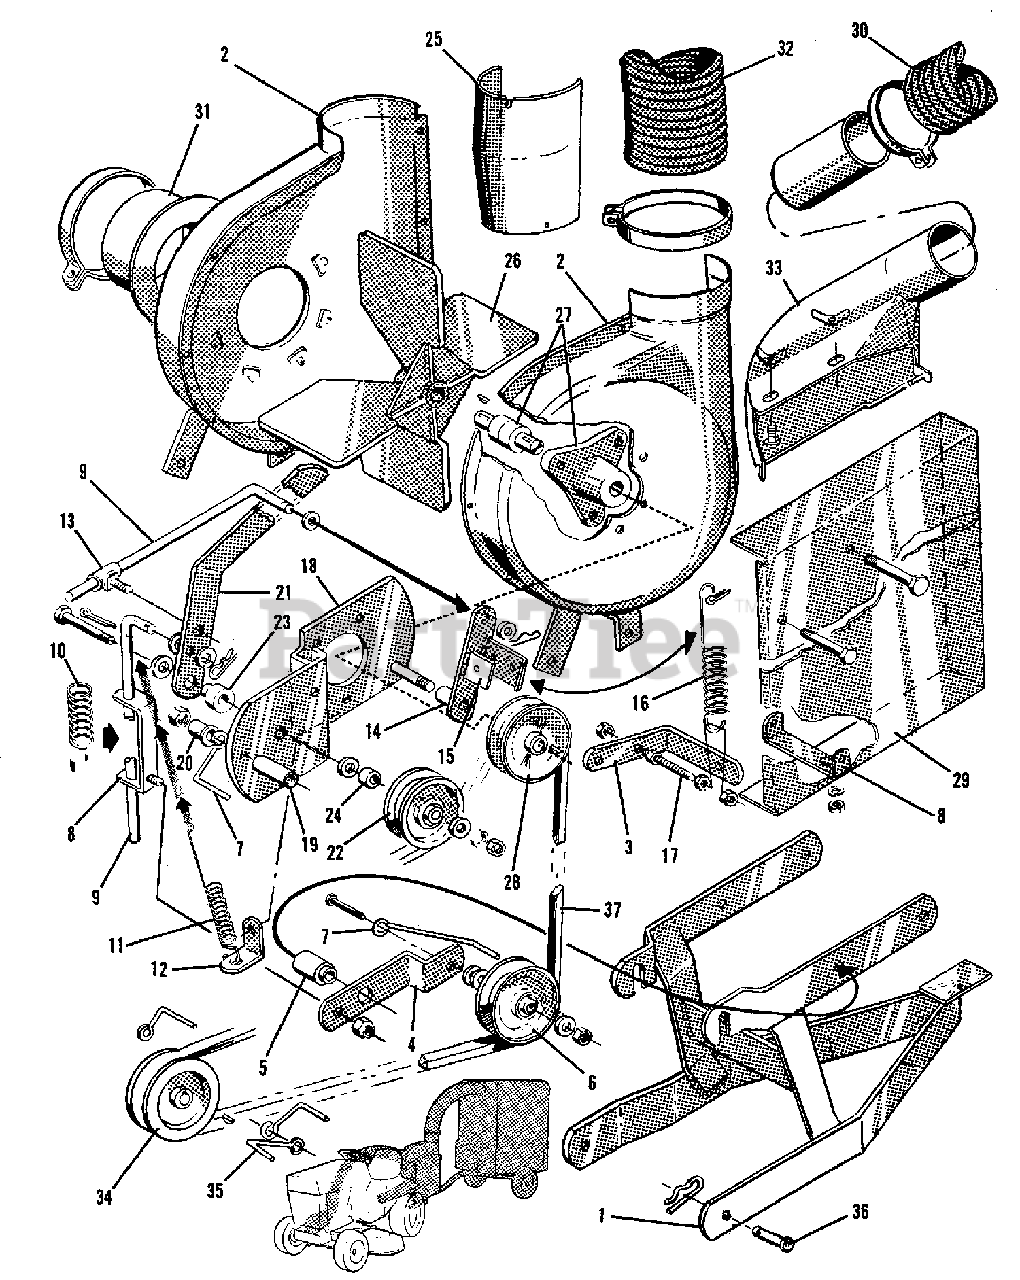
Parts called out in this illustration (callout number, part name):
1	SUPPORT ASSEMBLY, Blower Housing
1	CAPSCREW, 3/8 NC x 1-1/4
1	LOCKWASHER, 3/8
1	NUT, 3/8NC
2	HOUSING ASSEMBLY, Inlet Half (L.H.)
2	HOUSING ASSEMBLY, Blower Half (R.H.)
2	CAPSCREW, 1/4NC x 1/2
2	LOCKWASHER, 1/4
2	NUT, 1/4NC
3	BRACKET, Cover
3	CAPSCREW, 5/16NC x 3/4
3	CAPSCREW, 3/8 NC x 1-1/4
3	LOCKWASHER, 5/16
3	LOCKWASHER, 3/8
3	NUT, 5/16NC
3	NUT, 3/8NC
4	ARM, Idler Support
4	NUT, 5/16NC, Lock
5	PIVOT, Idler Arm
5	CAPSCREW, 3/8NC x 3
5	WASHER, 13/32 x 1-1/2 x 11 Ga.
5	LOCKWASHER, 3/8
5	NUT, 3/8NC
6	PULLEY, Idler
6	CAPSCREW, 3/8 NC x 1-1/2
6	WASHER, 13/32 x 7/8 x 14 Ga.
6	LOCKWASHER, 3/8
6	NUT, 3/8NC
7	STOP, Belt
8	BRACKET ASSEMBLY, Support
8	CAPSCREW, 5/16NC x 3/4
8	LOCKWASHER, 5/16
8	NUT, 5/16NC
8	NUT, 5/16NC, Lock
9	ROD, Control
9	COLLAR, Set
9	SETSCREW, 1/4NC x 3/8, Square Head
9	PIN, Quick
9	WASHER, 11/32 x 7/8 x 16 Ga.
10	SPRING, Compression
11	SPRING, Tension
11	PIN, Cotter
12	BRACKET, Spring Mounting
12	CAPSCREW, 1/4NC x 1
12	WASHER, 1/4, Plain
12	LOCKWASHER, 1/4
12	NUT, 1/4NC
13	GUIDE ASSEMBLY, Rod
13	NUT, 5/16NC, Lock
14	LEVER ASSEMBLY, Brake
15	SCREW, #10NC x 5/8
15	LOCKWASHER, #10
15	NUT, #10NC
16	SPRING, Tension
16	PIN, Cotter
17	STUD, Spring Retaining
17	NUT, 3/8NC, Lock
17	LOCKWASHER, 3/8
17	NUT, 3/8NC
18	BRACKET ASSEMBLY, Idler Support
18	WASHER, 13/32 x 7/8 x 14 Ga.
18	NUT, 3/8NC, Lock
18	CAPSCREW, 3/8NC x 1
18	LOCKWASHER, 3/8
19	SPACER, Long
19	CAPSCREW, 5/16NC x 4
19	CAPSCREW, 5/16NC x 2-1/2
19	WASHER, 11/32 x 7/8 x 16 Ga.
19	LOCKWASHER, 5/16
19	NUT, 5/16NC
20	SPACER, Short
21	LEVER, P.T.O.
22	PULLEY, Idler
22	CAPSCREW, 3/8NC x 2-1/2
22	WASHER, 13/32 x 1-1/2 x 11 Ga.
22	WASHER, 13/32 x 7/8 x 14 Ga.
22	LOCKWASHER, 3/8
22	NUT, 3/8NC
23	SPACER, Pivot
25	DEFLECTOR
25	SCREW, #10NC x 3/8, Self-Tap
26	FAN ASSEMBLY, Blower
26	SETSCREW, 5/16NC x 1/2, Square Head
26	KEY, #9, Woodruff
27	FLANGE ASSEMBLY
28	PULLEY, Blower Drive
28	SETSCREW, 5/16NC x 5/16
28	KEY, #9, Woodruff
29	COVER, Belt Drive
30	HOSE, Intake
30	CLAMP, Hose
30	SCREW, 1/4NC x 2-3/4, Round Head
30	LOCKWASHER, 1/4
30	NUT, 1/4NC
31	FLANGE, Hose
32	HOSE, Exhaust
32	CLAMP, Hose
32	SCREW, 1/4NC x 2-3/4, Round Head
32	LOCKWASHER, 1/4
32	NUT, 1/4NC
33	ADAPTER ASSEMBLY, Vacuum Collector
33	NUT ASSEMBLY, Wing
33	BOLT, 3/8NC x 1
33	LOCKWASHER, 3/8
33	NUT, 3/8NC
34	PULLEY, P.T.O.
34	KEY, 3/16 x 3/16 x 1, Parallel
35	STOP, Belt
35	CAPSCREW, 3/8NC x 1-1/4
35	WASHER, 13/32 x 7/8 x 14 Ga.
35	LOCKWASHER, 3/8
35	NUT, 3/8NC
36	PIN, Round Head
36	PIN, Quick
37	V-BELT, Blower Drive
